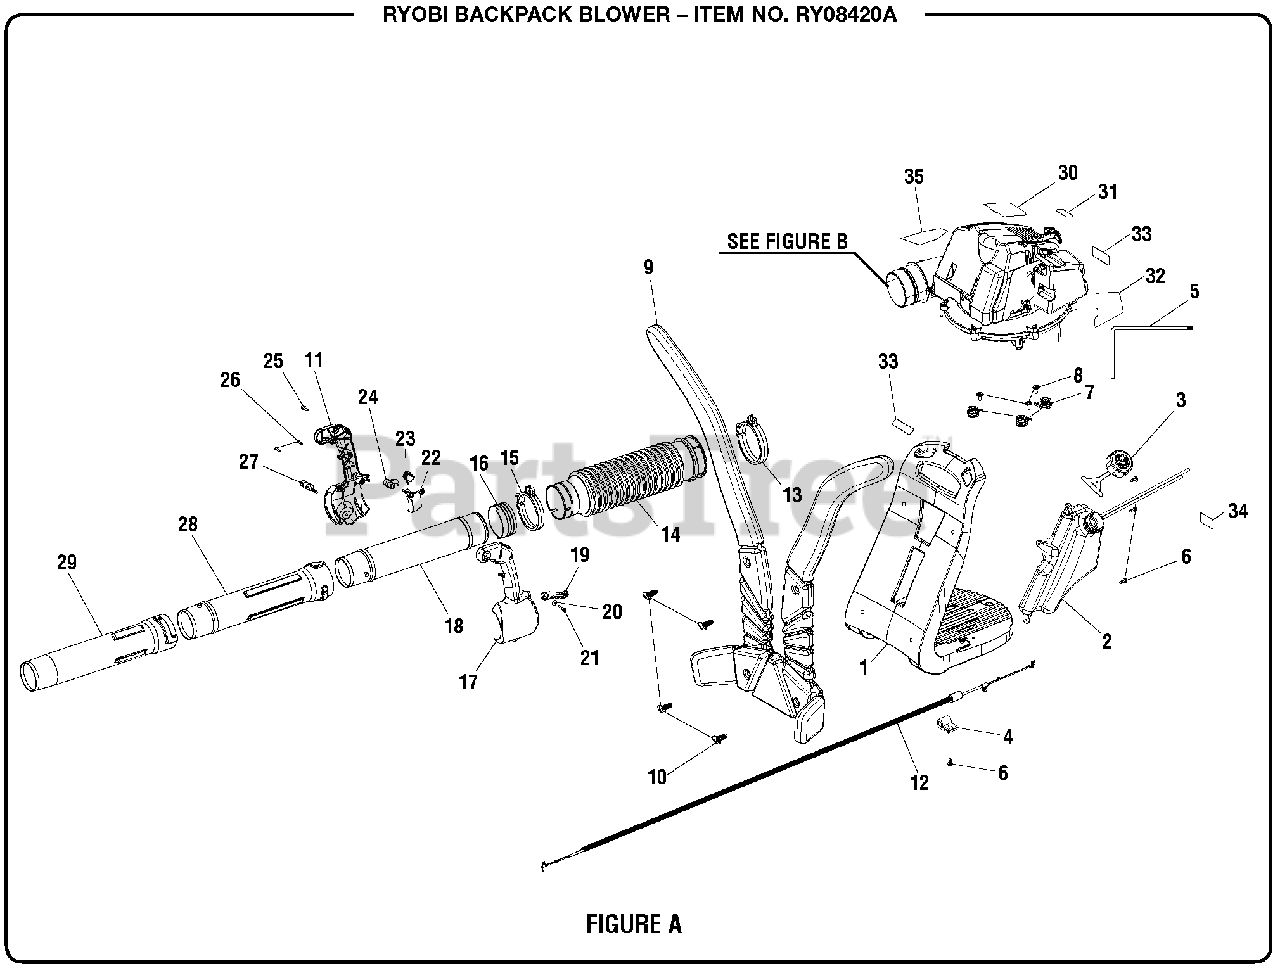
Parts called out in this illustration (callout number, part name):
2	Fuel Tank Assembly
3	Fuel Cap Assembly
4	Cable Clamp
5	Wrench (L-25)
6	Screw (10-14 x 14 mm)
8	Screw (10-14 x 16 mm)
10	Harness Snap Fastener
11	Right Hand Handle
12	Throttle Cable
13	Clamp Assembly (Large)
15	Clamp Assembly (Small)
16	Upper Blower Tube Bushing
17	Left Hand Handle
18	Upper Tube
19	Cruise Lever
20	Washer (OD12 x ID4.3 x 1.5t)
21	Screw (8-14 x 25 mm)
23	Stop Switch
24	Trigger Lock
25	Screw (10-14 x 3/4 in.)
26	Screw (M4 x 16 mm, Pan Hd.)
28	Intermediate Tube
29	Tube Nozzle
30	Model Label
31	Choke Label
32	Start Instructions Label
33	Logo Label
34	Warning Label
35	Combustion Warning Label
